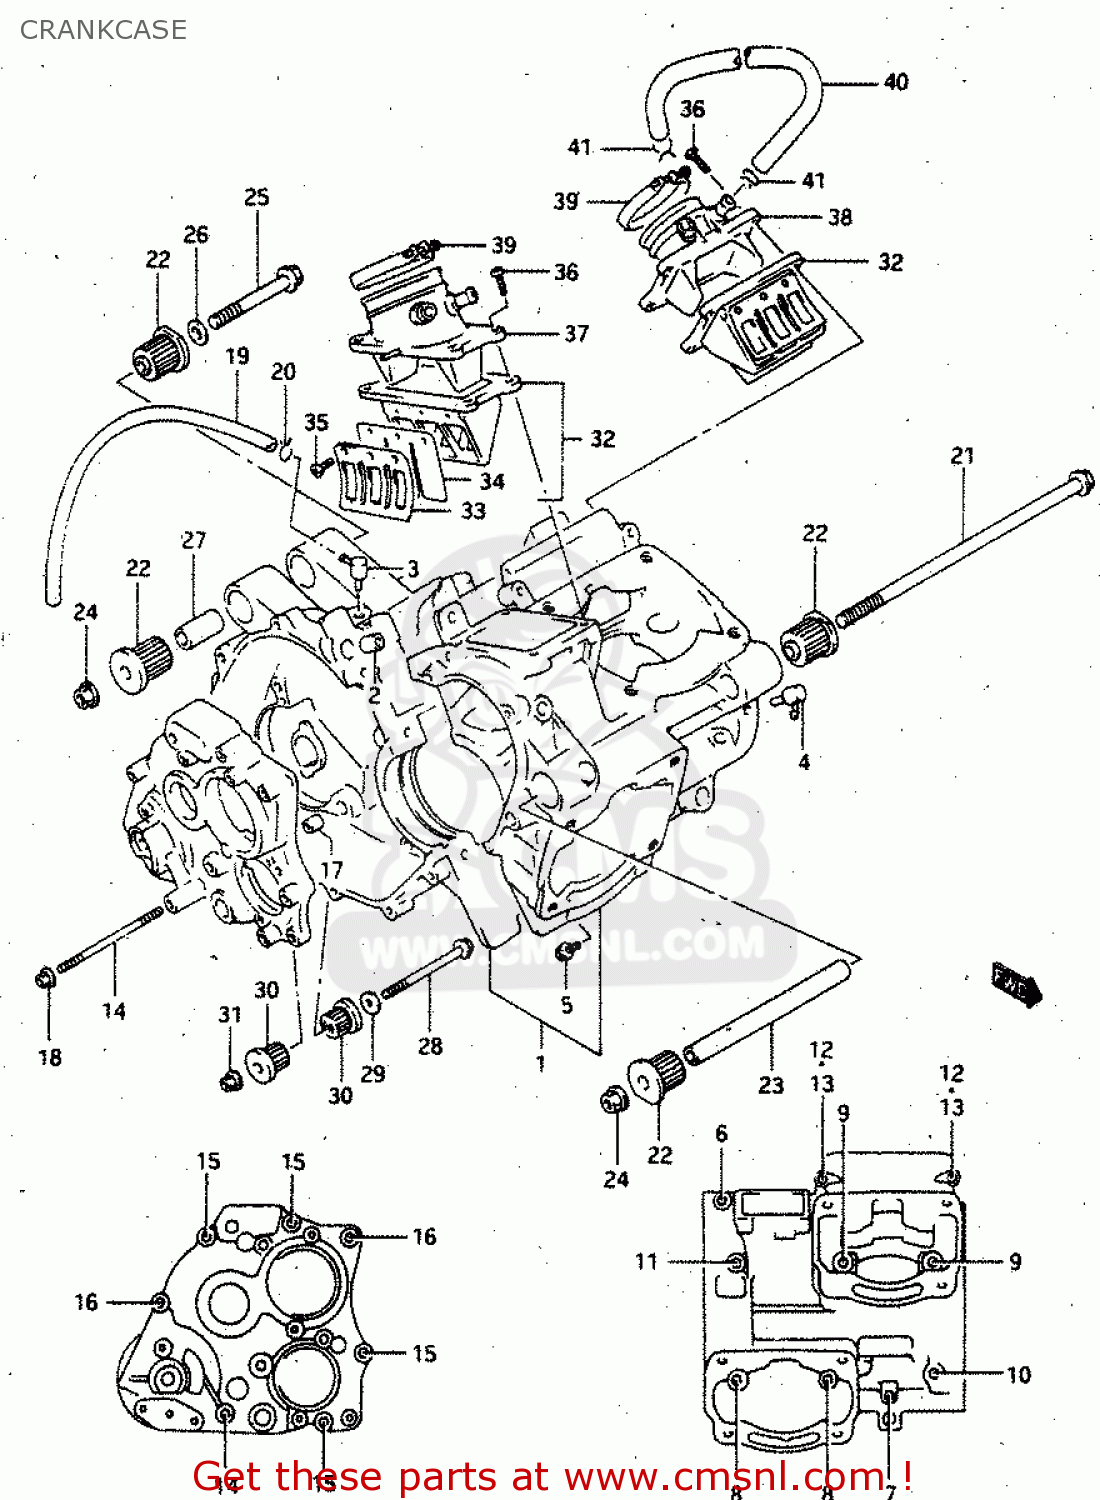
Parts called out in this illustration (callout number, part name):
1	CRANKCASE SET
2	PIN(10.4X13X22)
3	UNION,BREATHER HOSE
4	VALVE,OIL HOSE CHECK
5	BOLT
6	BOLT
7	BOLT
8	BOLT
9	BOLT
10	BOLT
11	BOLT 8X110
12	STUD
13	NUT
14	BOLT,STUD
15	BOLT,STUD
16	STUD BOLT
17	PIN(8.4X11X18)
18	NUT
19	HOSE (4.5X8.5X600)
20	CLIP
21	BOLT(10X225)
22	BUSH
23	SPACER
24	NUT
25	BOLT(10X130)
26	WASHER
27	SPACER,10.2X16
28	BOLT(8X70)
29	WASHER
30	BUSH
31	NUT
32	VALVE ASSY,REED
33	STOPPER,REED VALVE
34	VALVE,REED
35	SCREW
36	SCREW
37	PIPE,INTAKE,R
38	PIPE,INTAKE,L
39	CLAMP
40	HOSE (9X14X2200)
41	CLIP
